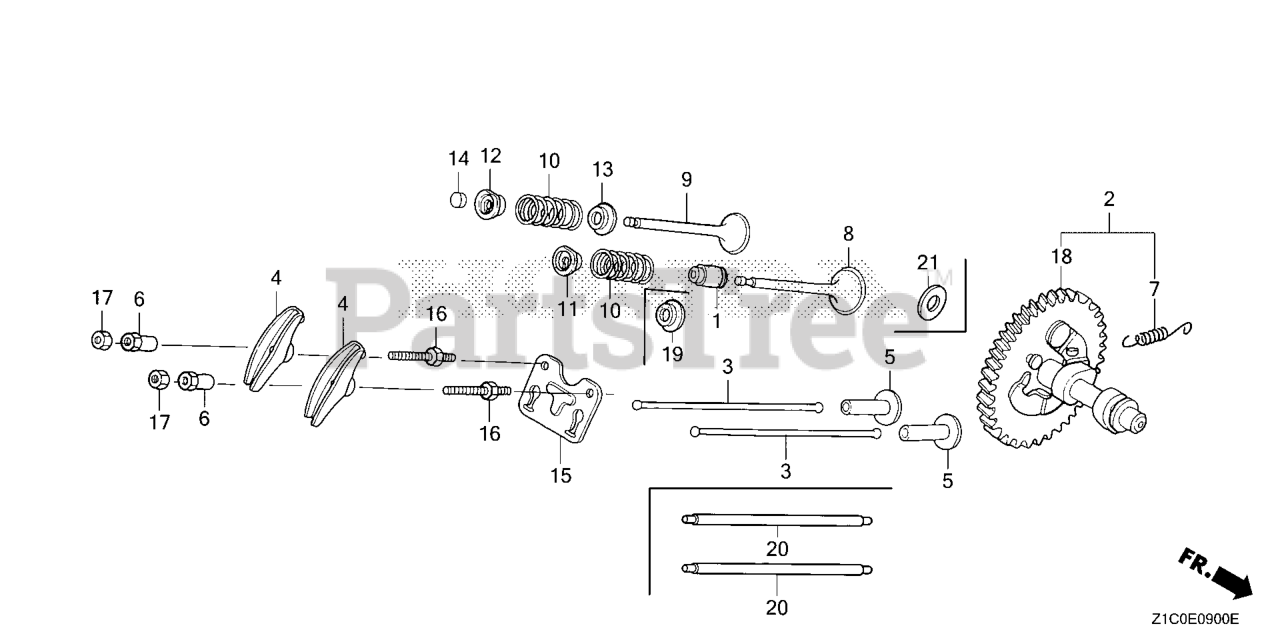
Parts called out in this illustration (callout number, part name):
1	SEAL, VALVE STEM
4	ARM, VALVE ROCKER
5	LIFTER, VALVE
6	PIVOT, ROCKER ARM
8	VALVE, IN.
9	VALVE, EX.
10	SPRING, VALVE
11	RETAINER, IN. VALVE SPRING (EXHAUST SIDE)
12	RETAINER, IN. VALVE SPRING (EXHAUST SIDE)
13	SEAT, VALVE SPRING
15	GUIDE, PUSH ROD
16	BOLT, PIVOT (8MM)
17	NUT, PIVOT ADJ.
18	CAMSHAFT (STD)
18	CAMSHAFT COMP (STD)
